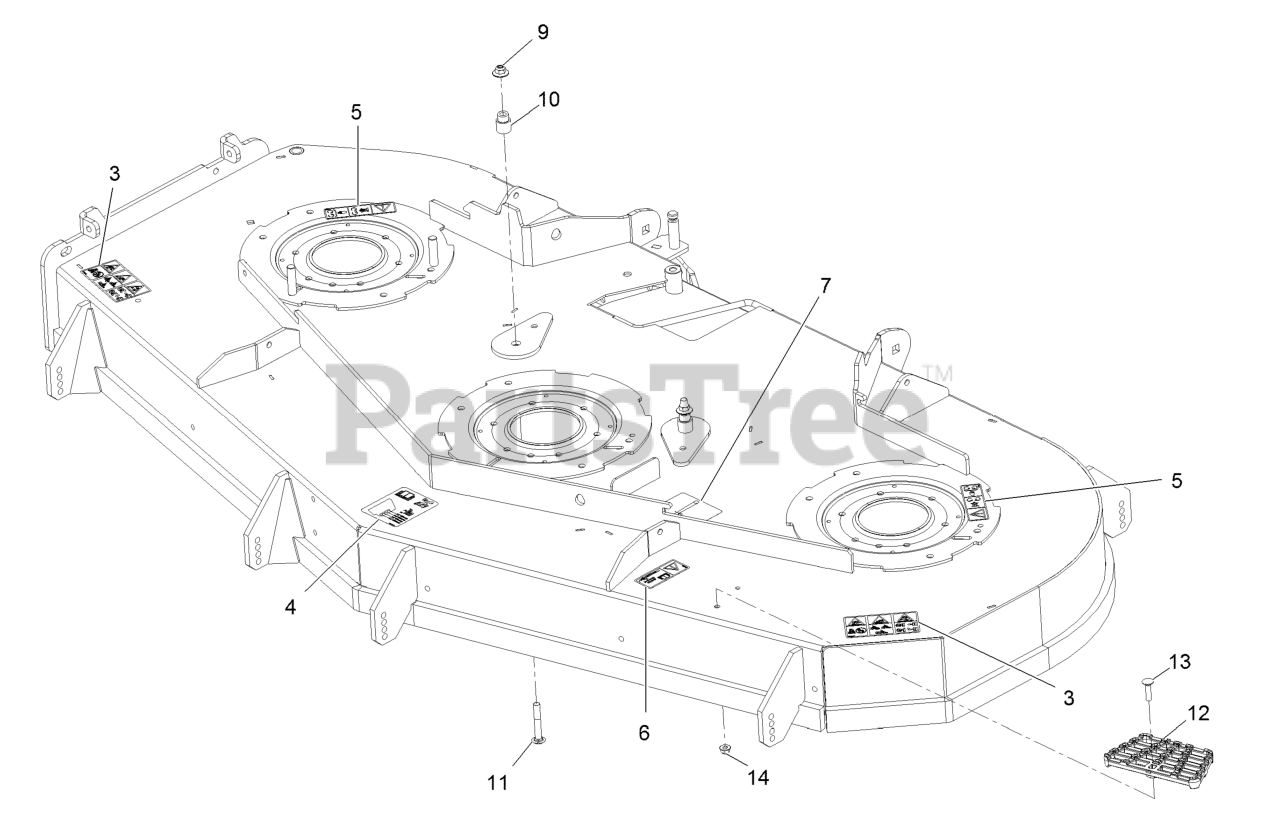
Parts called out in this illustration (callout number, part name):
3	DECAL-DANGER THROWN OBJECTS
4	DECAL-ROLLER, ANTI-SCALP
5	DECAL-COVER, MISSING
6	DECAL-BOLT TORQUE
7	DECAL-BELT ROUTING
9	Nut-Nyloc 3/8-16 Flg
10	BUSHING-IDLER
11	SCREW-CARR
12	STEP-DECK
13	Bolt-Carriage 5/16-18 X 1 1/4
14	NUT-HF, NI
